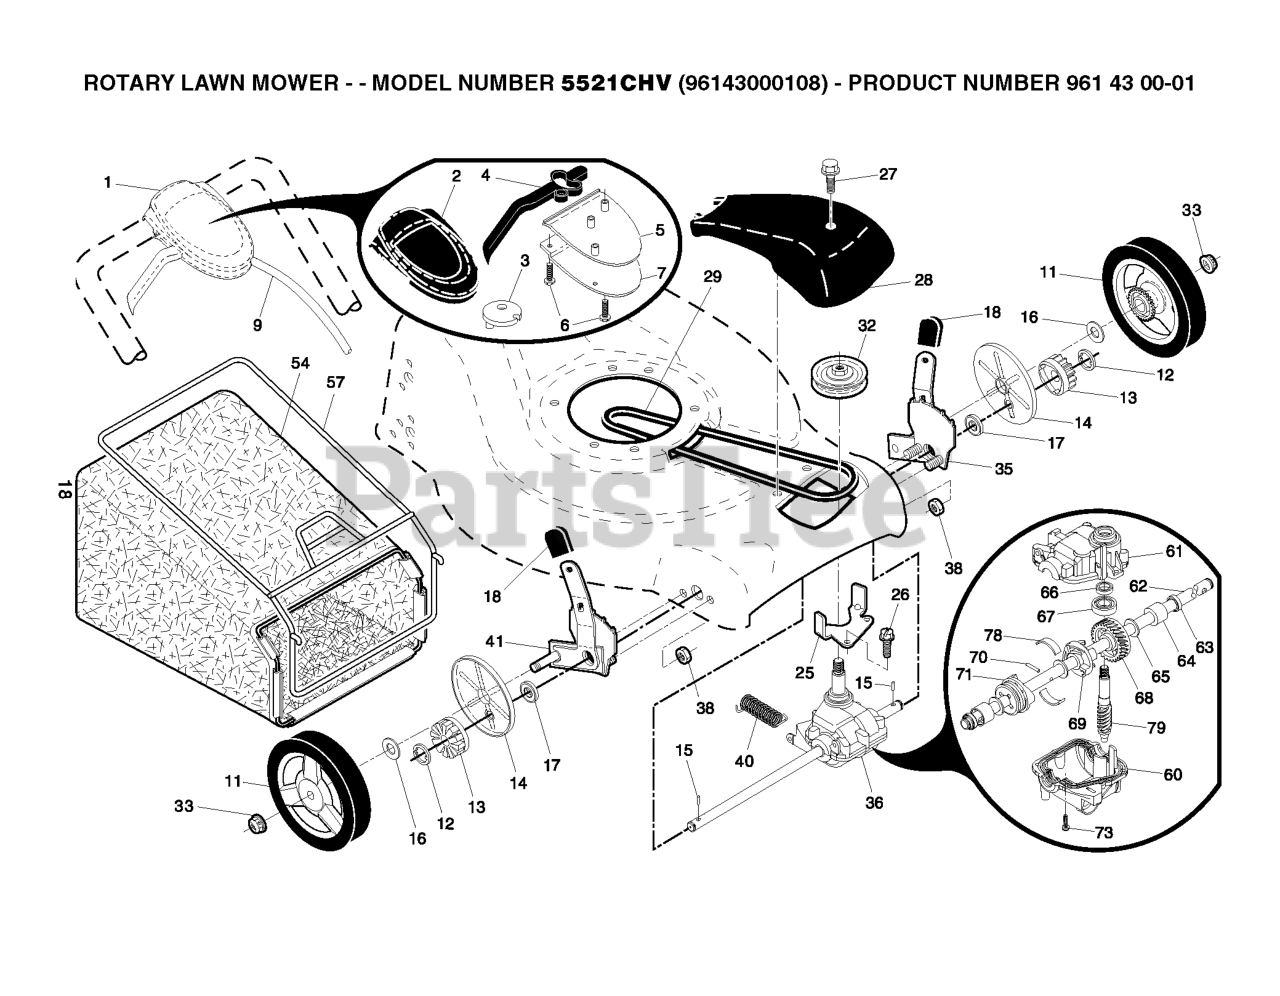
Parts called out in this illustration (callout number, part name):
1	DRIVE CONTROL ASSEMBLY (INCLUD
2	COVER TOP AUTO WALK CONTROL
3	PULLEY.CAM.DRIVE.CONTROL.EZ
4	LEVER, AUTOWALK DRIVE CONTROL
5	CASE BOTTOM
6	SCREW, PHILLIPS HEAD 10 X 5/8
7	BRACKET.DRIVE.CONTROL.MOUNT.BL
9	CABLE ASSEMBLY, DRIVE
11	WHEEL.8X1.75.H3SPK.RAD3.GY.BU3
12	E-RING 7/16 RE
13	PINION.14.TEETH.FGD
14	COVER.DUST.WHEEL
15	PAWL, DRIVE
16	WASHER FLUT
17	BEARING
18	SELECTOR KNOB
25	BELT KEEPER
27	SCREW, HEX HD TAPPING #10-24 1
28	COVER.DRIVE.21.FWGD.GRAY
29	BELT.DRIVE.FG
32	RP PULLEY.DRIVE.EZ
33	NUT.HEX.FLANGE.3/8-16.LO(3 2)
35	WHEEL ADJ KIT LH
36	TRANSMISSION.21.FGD.HT.VST
38	LOCKNUT.NYLOC.1/4-20
41	WHEEL ADJ KIT RH
54	GBAG.34710247.SILVER.H
57	FRAME.GBAG.21.FWGD
60	CASE.BOTTOM.
61	CASE.UPPER.00254(SERVICE)
62	SHAFT OUTPUT (12289)
63	SEAL.OUTPUT.SHAFT
66	SEAL INPUT SHAFT
68	GEAR 28 TEETH 36208
69	FIXED DOG CLUTCH
70	PIN.3.50.33733
71	MOVEABLE DOG CLUTCH
78	SPRING LEAF
79	SHAFT WORM
